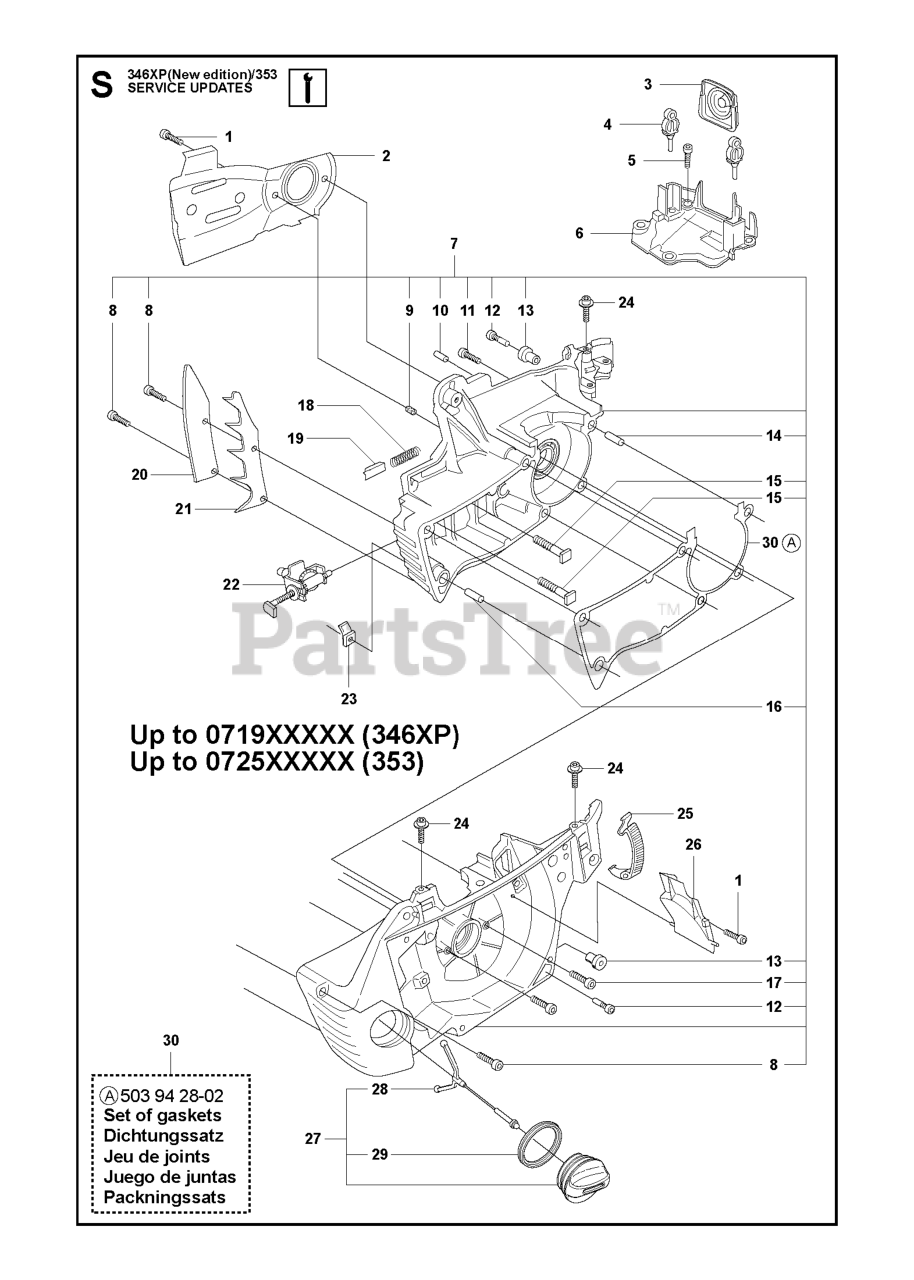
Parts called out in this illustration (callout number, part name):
7	CRANKCASE ASSY.
13	MOVEMENT LIMITER
18	LOCK SPRING
22	CHAIN TENSIONER
23	CHAIN CATCHER
25	BUCKLE ORANGE
27	OIL TANK CAP GREY
29	OILCAP GASKET
30	GASKET SET
